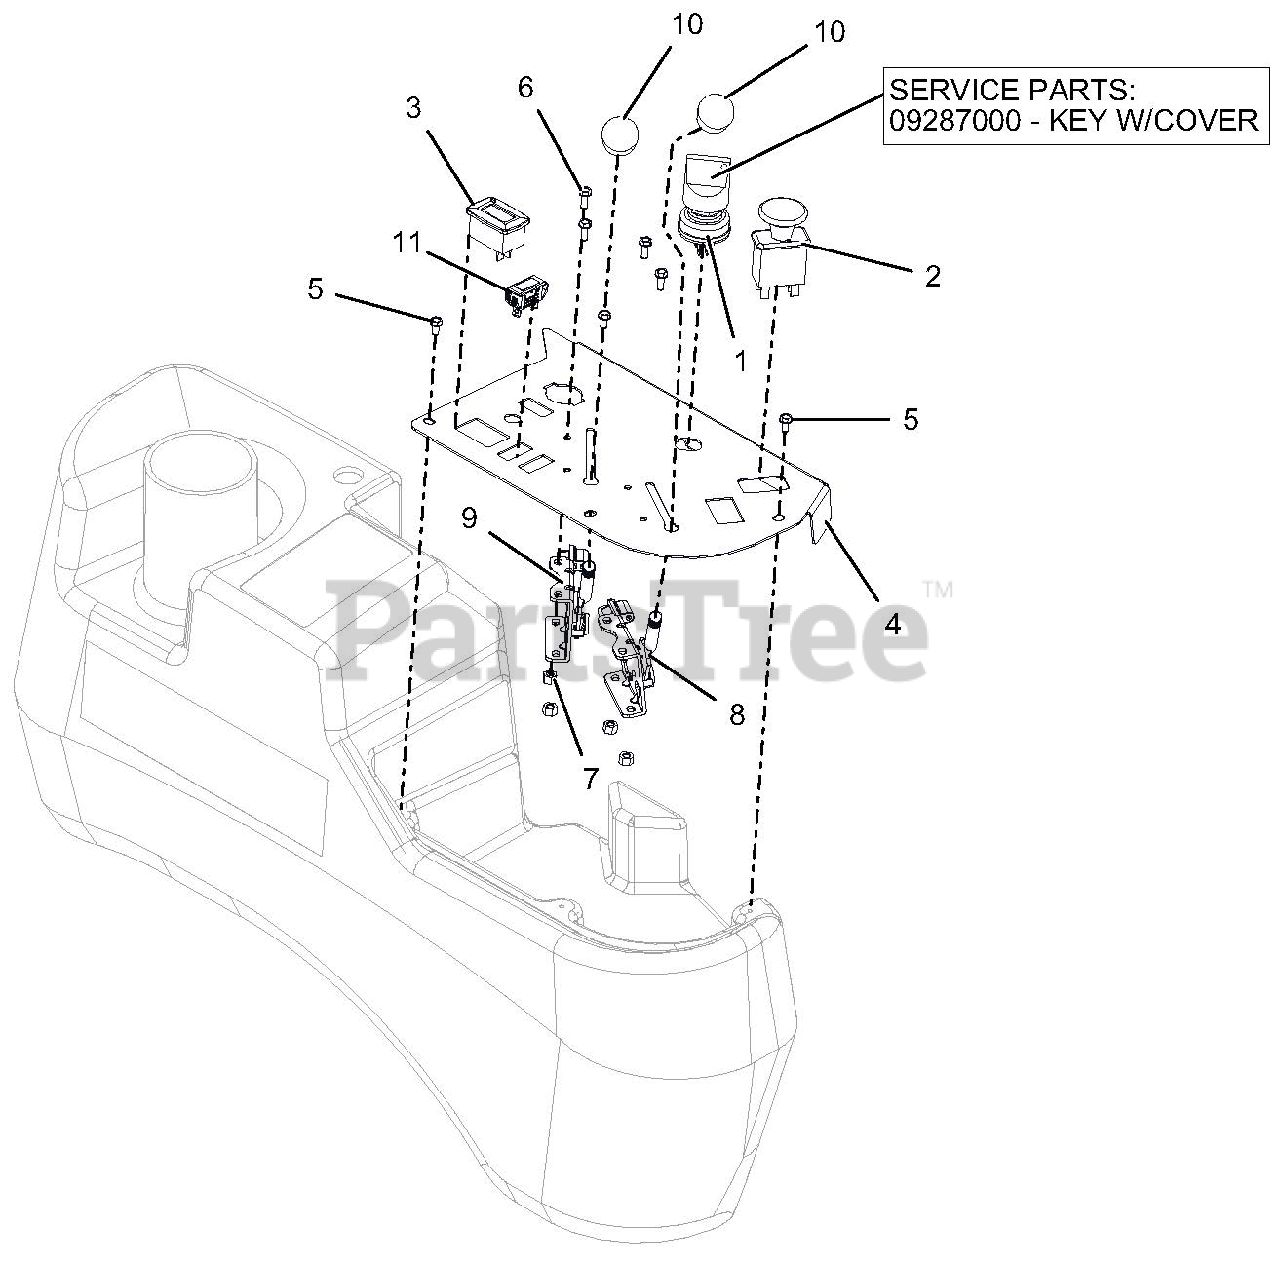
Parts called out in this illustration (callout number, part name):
1	SWITCH, IGNITION
1	KEY W/COVER
2	SWITCH, CLUTCH
3	METER, HOUR W/MAINTENANCE
4	PANEL, CONTROL
5	SCR-MCH 10-24X.38 HWHSTAINLESS
6	@SCR-MCH 10-24X.50 HWH YWZC
7	NUT-LK-NYL #10-24 YWZC
8	CABLE, THROTTLE 53"
9	CABLE, PRO-CONTROL THROTTLE
10	KNOB, CONTROL BLACK .38-16X.50
11	LIGHT, INDICATOR
